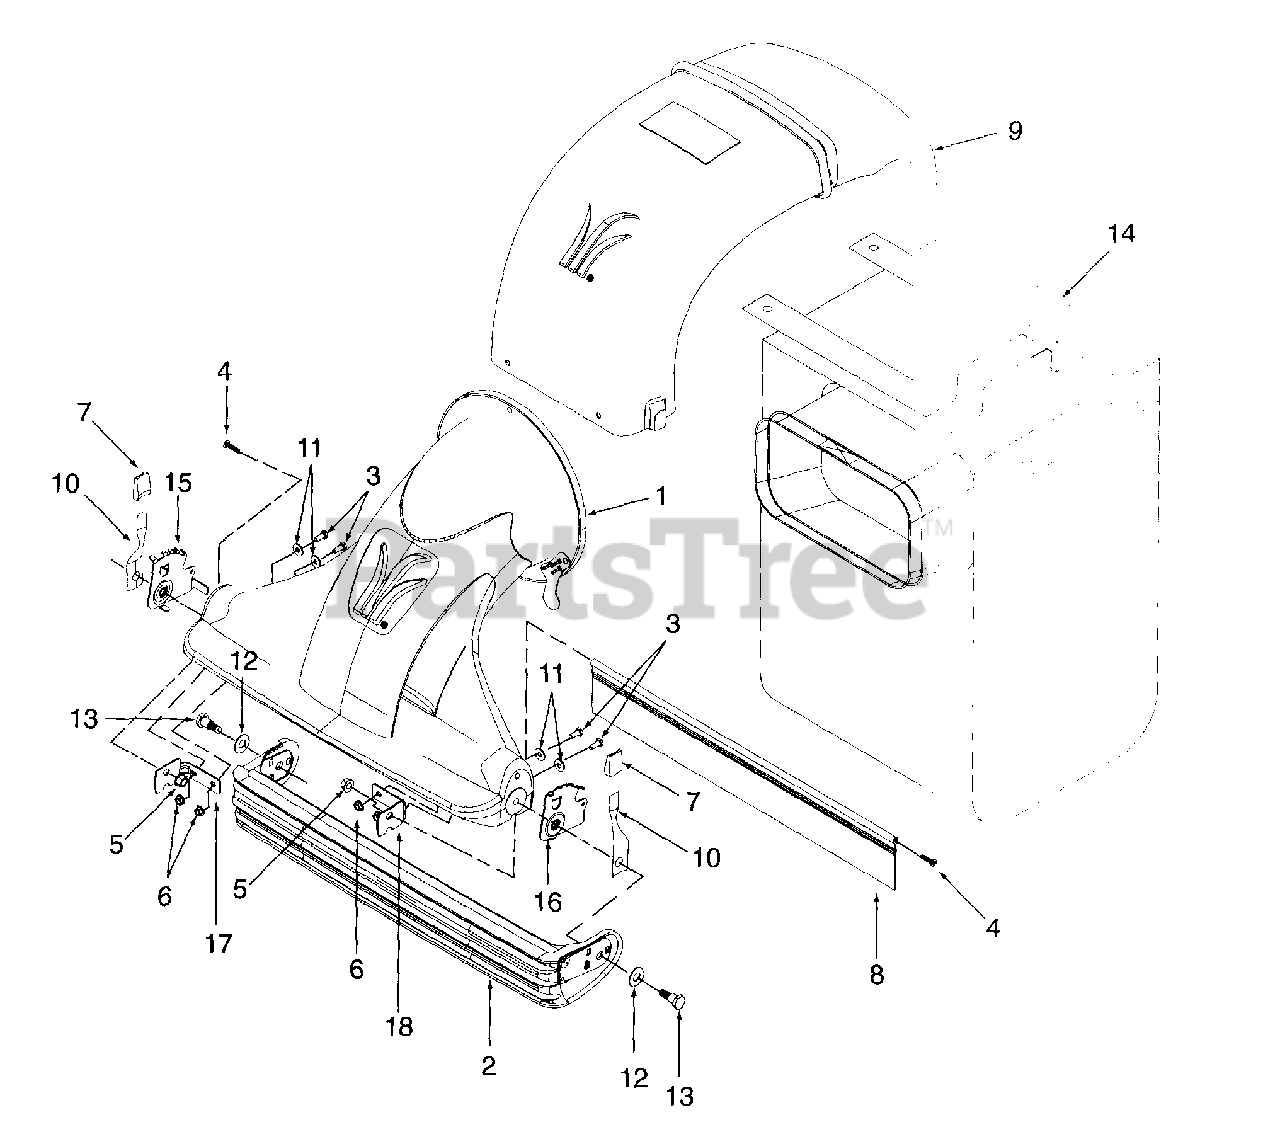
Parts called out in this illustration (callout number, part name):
1	Nozzle Assembly, Black
2	Door Assembly, Black
3	Screw, Hex Cap, 1/4-20 x .625
4	Screw, Truss Hd Tapp
5	Nut, Hex Flange Lock, 3/8-16
6	Nut, Hex Flange Lock, 1/4-20
7	Knob, Height Adj.
8	Flap, Nozzle Rear
9	Discharge Chute
10	Spring Lever
11	Washer, Flat, .28 x .74 x .06
12	Washer, Flat, .510 x 1.20 x .060
13	Screw, Shoulder, .50 x .545 x 3/8-16
14	Bag, 3 Bushel
17	Bracket, Nozzle Reinforcement RH
18	Bracket, Nozzle Reinforcement LH
